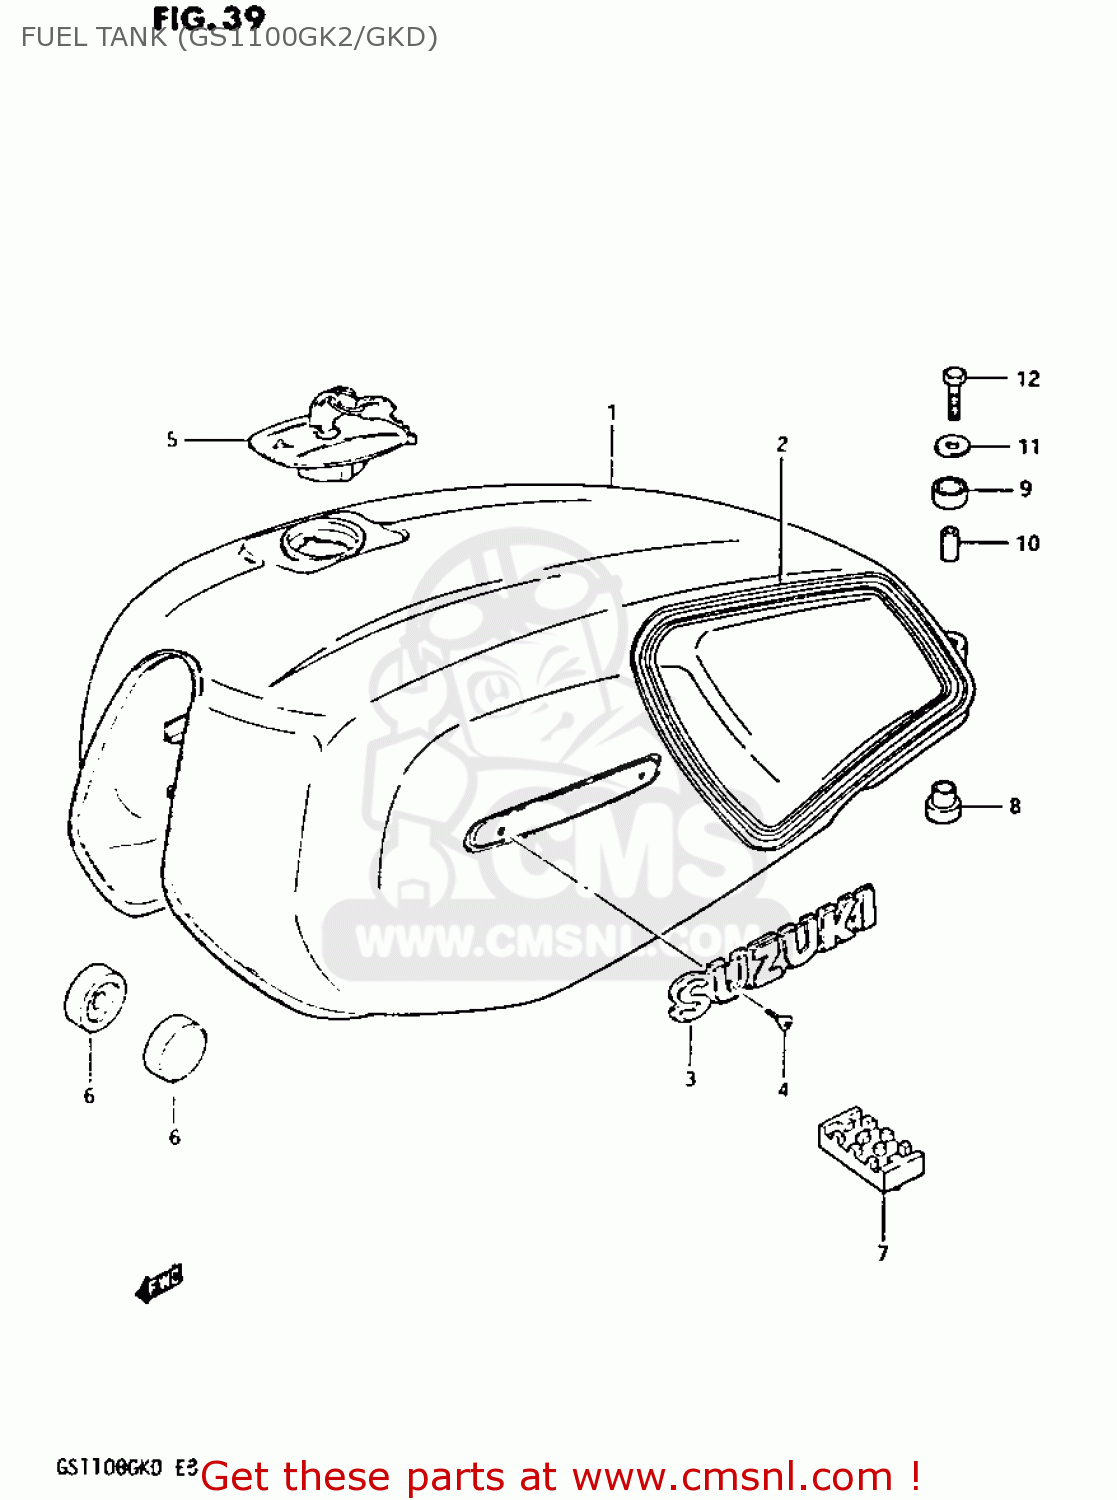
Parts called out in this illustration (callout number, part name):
1	TANK ASSEMBLY,FUEL
2	TAPE SET,FUEL TANK
3	EMBLEM
4	SCREW 3X6
5	CAP SET,FUEL TANK
6	CUSHION
7	CUSHION,FUEL TANK
9	CUSHION
10	SPACER (6.4X9X21.5)
11	WASHER (6.5X24X1.6)
12	BOLT
